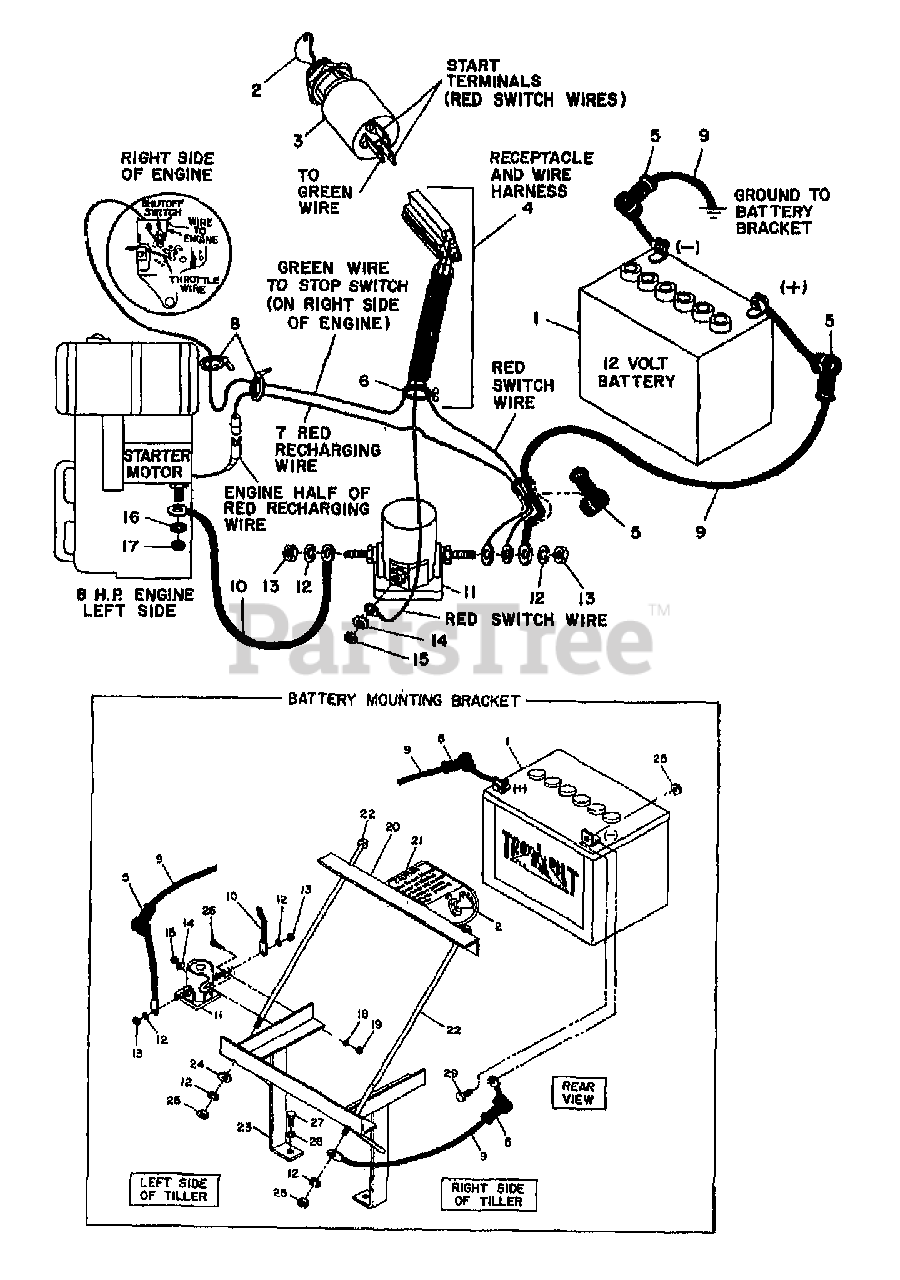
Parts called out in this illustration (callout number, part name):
1	KIT-VENTED BATTERY
2	KEYS(1 PAIR) FOR SWITCH
3	KEYSWITCH W/KEYS
4	ASSM-HARNESS 2647/20857
6	TIE-TWIST LOCK
7	WIRE-RECHARGE 5&7 BRIGGS
8	TIE-CABLE NYLON BLACK
9	CABLE-BATTERY
10	CABLE-BATTERY
11	KIT-SOL W/HDW
12	WASHER-LK .312 ZP
13	NUT-HEX 5/16-24
14	WASHER-EXTERNAL TOOTH 1
15	NUT-HH M10-32X.125
16	LOCKWASHER 1/4"
17	NUT HEX 1/4"-20
18	WASHER-LK .25 ZP
19	NUT-HEX 1/4-20 ZP
20	KEYSWITCH PLATE/CLAMP-WELD
21	DECAL-KEYSWITCH TILLER
22	SCR-HH 5/16-18 X 9
23	KIT-BATTERY BRKT HORSE
24	WASHER-FLAT 5/16 SAE
25	NUT-HEX 5/16-18 ZP
26	SCR-RH 1/4-20 X .75 ZP
27	BOLT-HH 3/8-16X1.5 FTH ZP
28	WASHER-LK .375 @ DEPL
29	SCR-HHC 5/16-18X.75 GR 5 ZP
